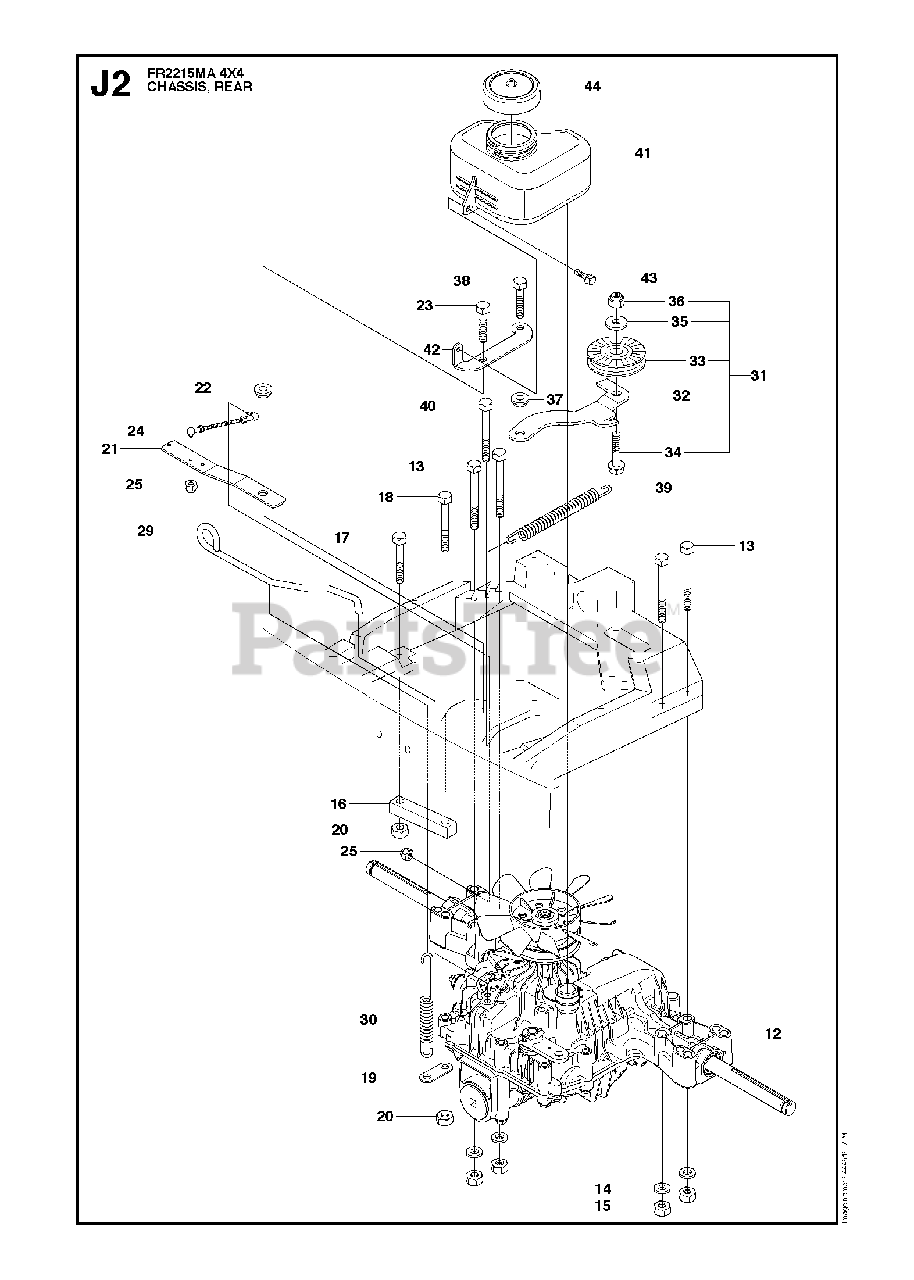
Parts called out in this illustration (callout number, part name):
12	HYDRAULMOTOR
14	WASHER BRB 8.4X17
15	NUT
19	CONNECTOR
20	NUT
22	WASHER
23	SCREW 8X20
25	LOCKNUT M5
30	SPRING
31	TENSIONER
32	TENSIONER
33	PULLEY
34	SCREW
35	SPACER
36	LOCKNUT M8
37	WASHER
38	SCREW 8X20
39	SPRING
41	TANK
